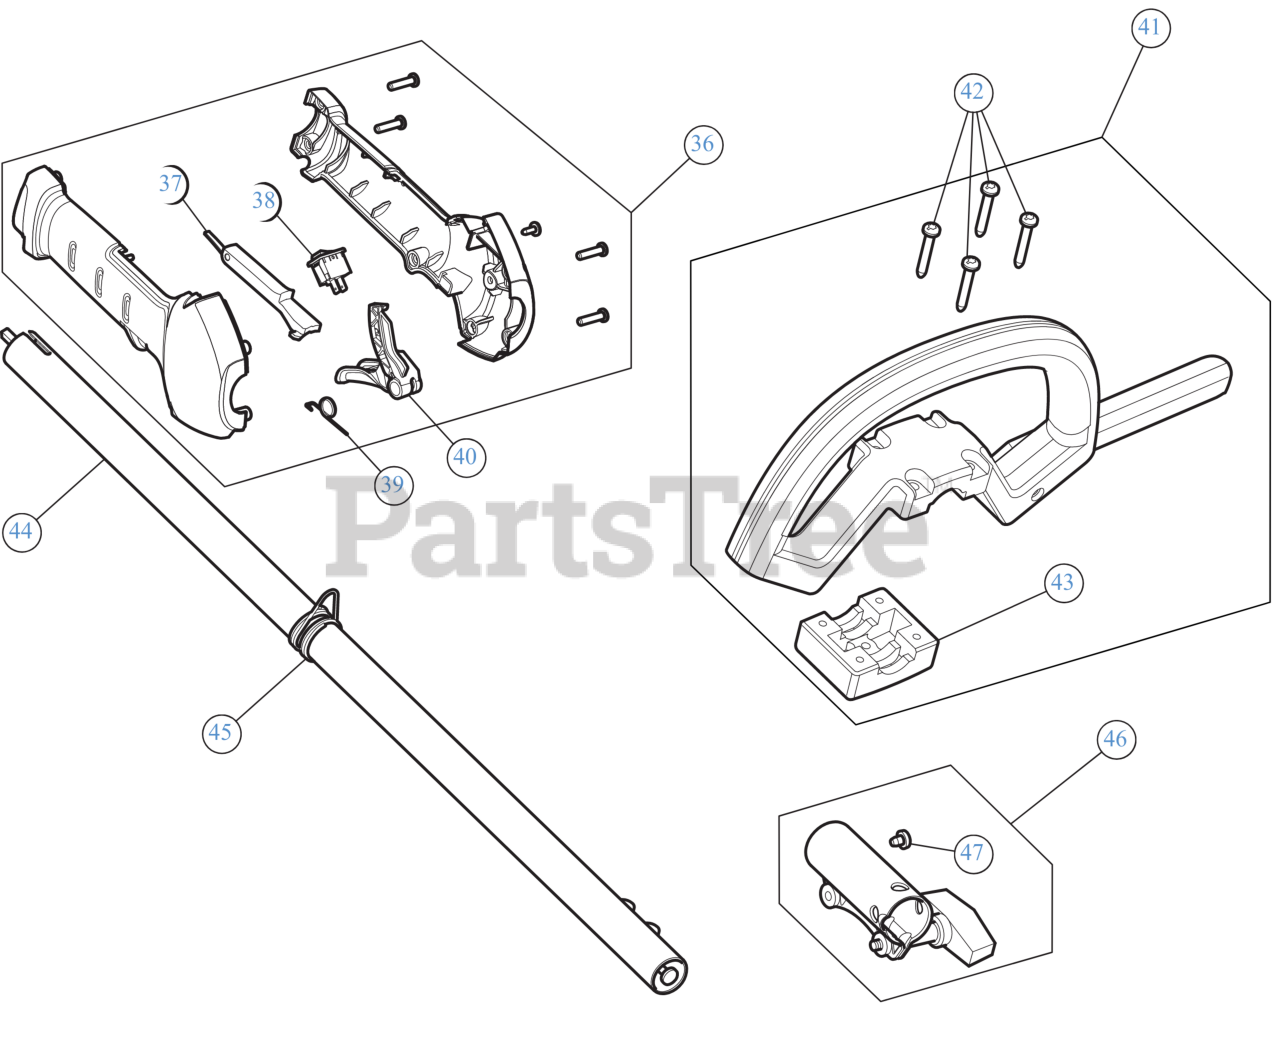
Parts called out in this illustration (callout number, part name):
36	THROTTLE HOUSING ASSEMBLY
37	LEVER LOCK OUT
38	SW, MOMENTARY ON/O
39	TRIGGER SPRING
40	THROTTLE TRIGGER
41	HANDLE:D
43	HANDLE BASE
44	BOOM ASSEMBLY UPR
45	CLAMP-SHOULDER STR
46	CLICK LINK
47	SCREW, 10-32X.250 TA
